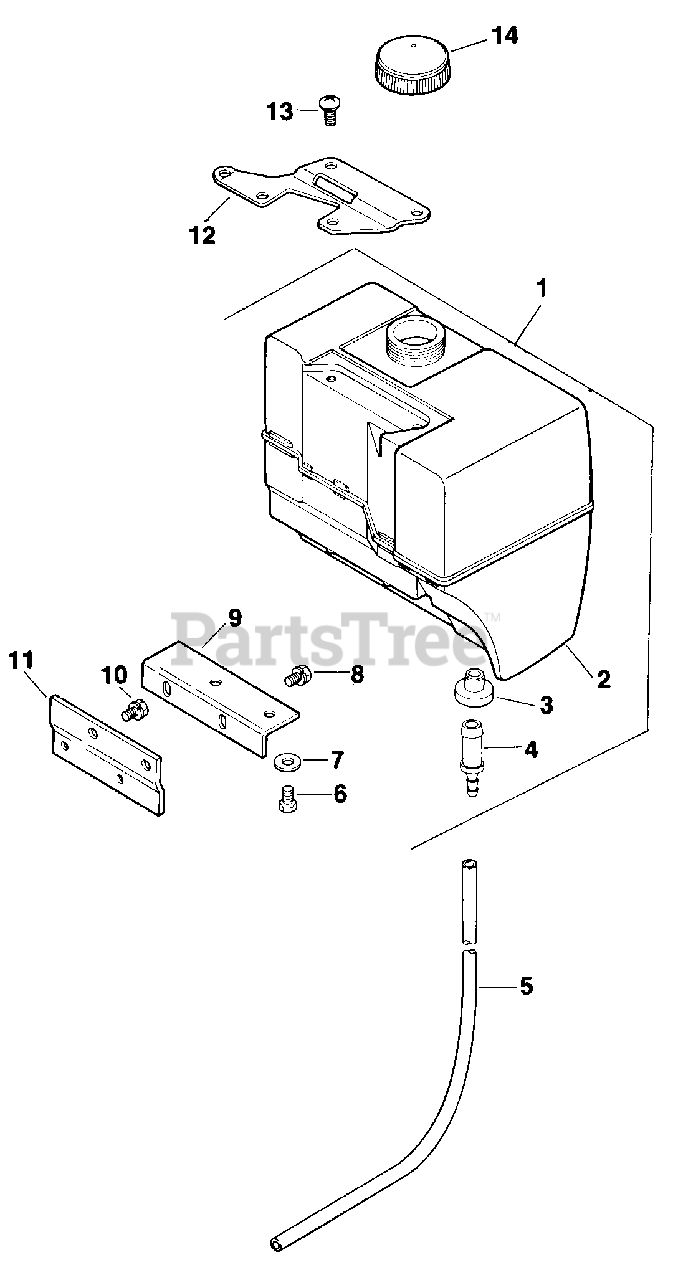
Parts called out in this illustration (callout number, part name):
1	Kit, Fuel Tank (Includes 2-4 & 9)
2	Fuel Tank Assembly (Includes 3 & 4)
3	Bushing, Fuel Tank
4	Fitting, Straight Fuel
6	Screw, H.C. 1/4-20 x 5/8
7	Washer, Plain 1/4
8	Screw, H.C. Sems 1/4-20 x 3/8
9	Bracket, Fuel Tank
10	Screw, H.C. Sems 1/4-20 x 3/4
11	Bracket, Lower Tank
12	Bracket, Upper Tank Support
13	Screw, Pozidrive T.H. 1/4-20 x 5/8
14	Cap, Fuel Tank
